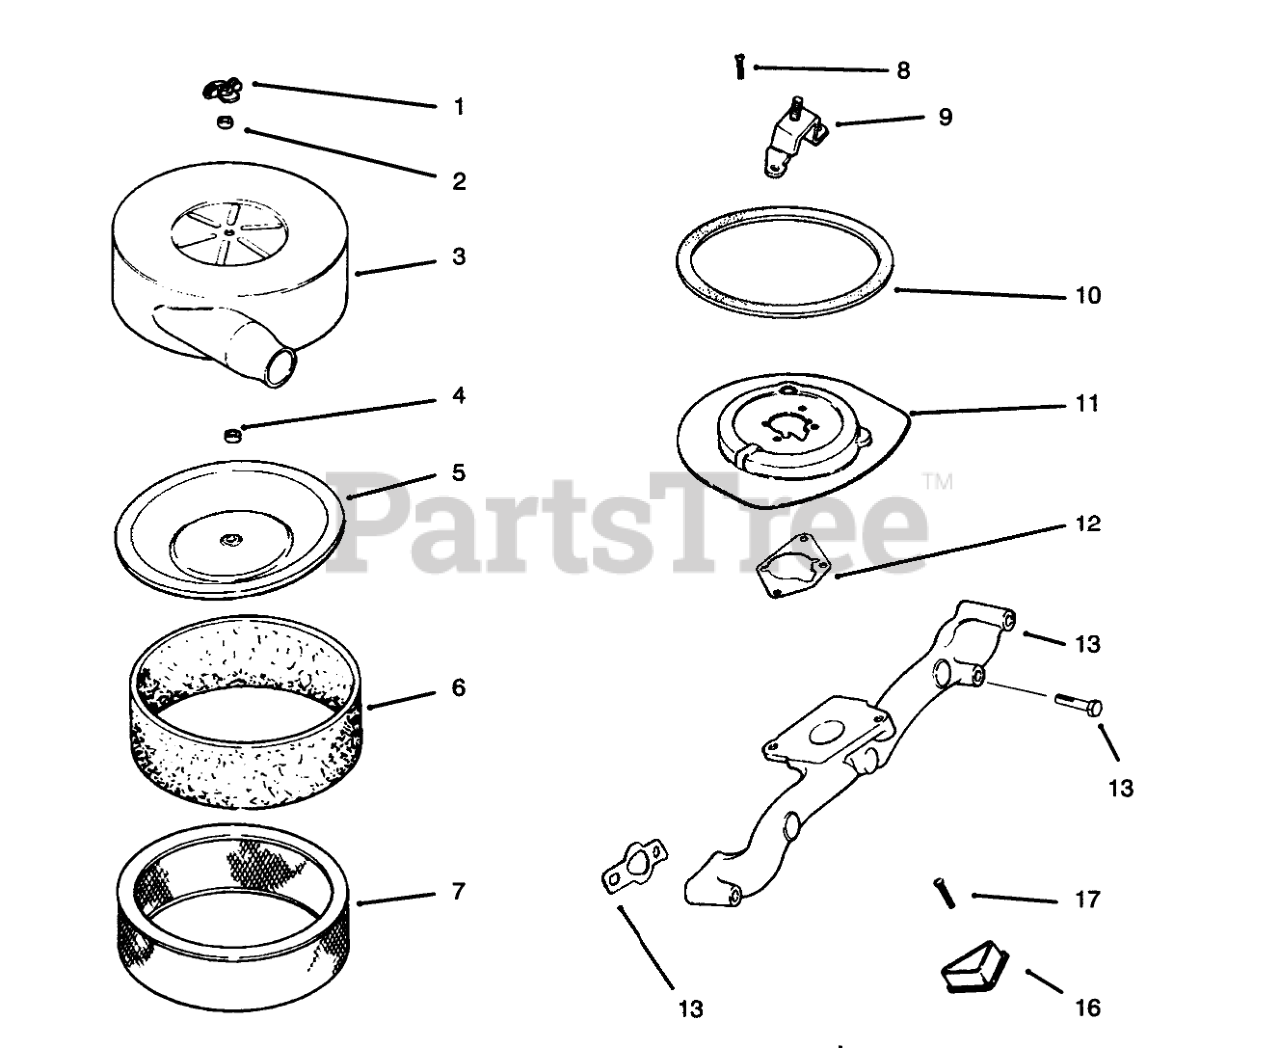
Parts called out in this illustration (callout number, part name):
1	Nut-Wing
2	Seal
3	Cover-Air Cleaner
4	Seal
5	Cover-Inner Air Cleaner
6	Element-Precleaner
7	Element-Air Cleaner
8	Screw
9	Bracket-Air Cleaner
10	Seal-Air Cleaner
11	Base-Air Cleaner
12	Gasket-Air Cleaner
13	Gasket-Intake Manifold
14	Screw
15	Manifold
16	Cover-Blower Housing
